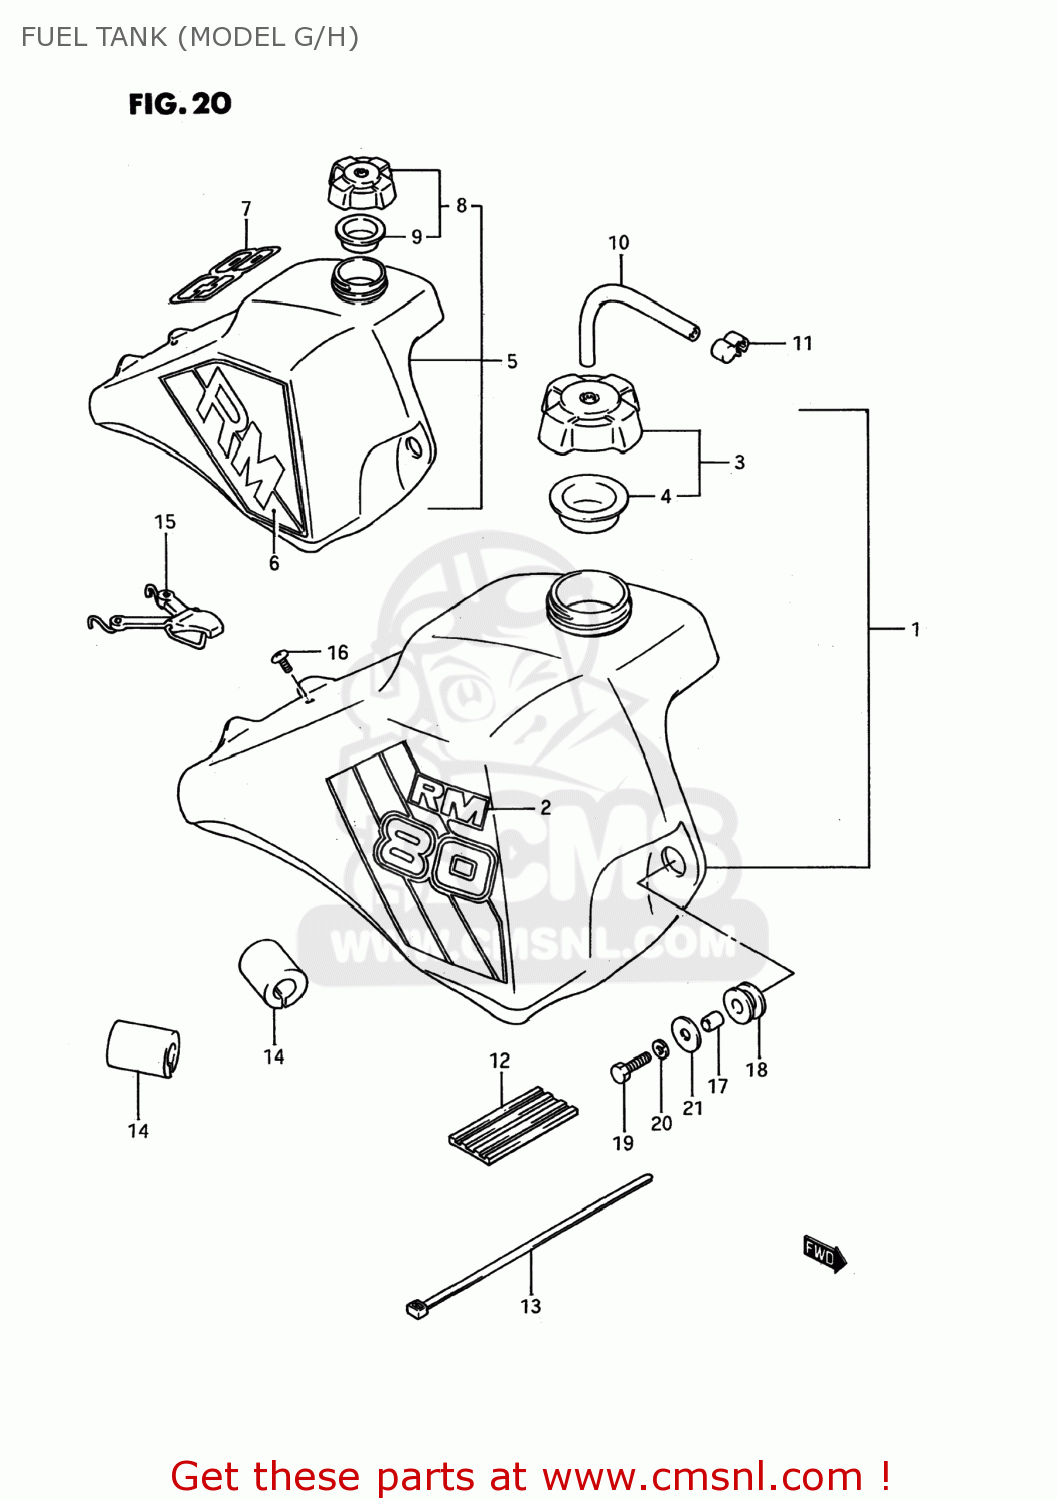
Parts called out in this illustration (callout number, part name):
1	TANK ASSEMBLY,FUEL
2	TAPE SET,FUEL TANK
3	CAP SET,FUEL TANK
4	GASKET,FUEL TANK CAP (NAS)
5	TANK ASSEMBLY,FUEL
6	TAPE SET,FUEL TANK STRIPE
7	EMBLEM,FUEL TANK
8	CAP SET,FUEL TANK
9	GASKET,FUEL TANK CAP (NAS)
10	HOSE
11	CLAMP,FUEL TANK BREATHER HOSE
12	CUSHION,FUEL TANK UPR FR
13	CLAMP
14	CUSHION,FUEL TANK UPR RR
15	BAND,FUEL TANK RR
16	SCREW (6X15)
17	SPACER (6.8X10X11.5)
18	CUSHION
19	BOLT
20	WASHER,LOCK
21	WASHER (6.5X24X1.6)
